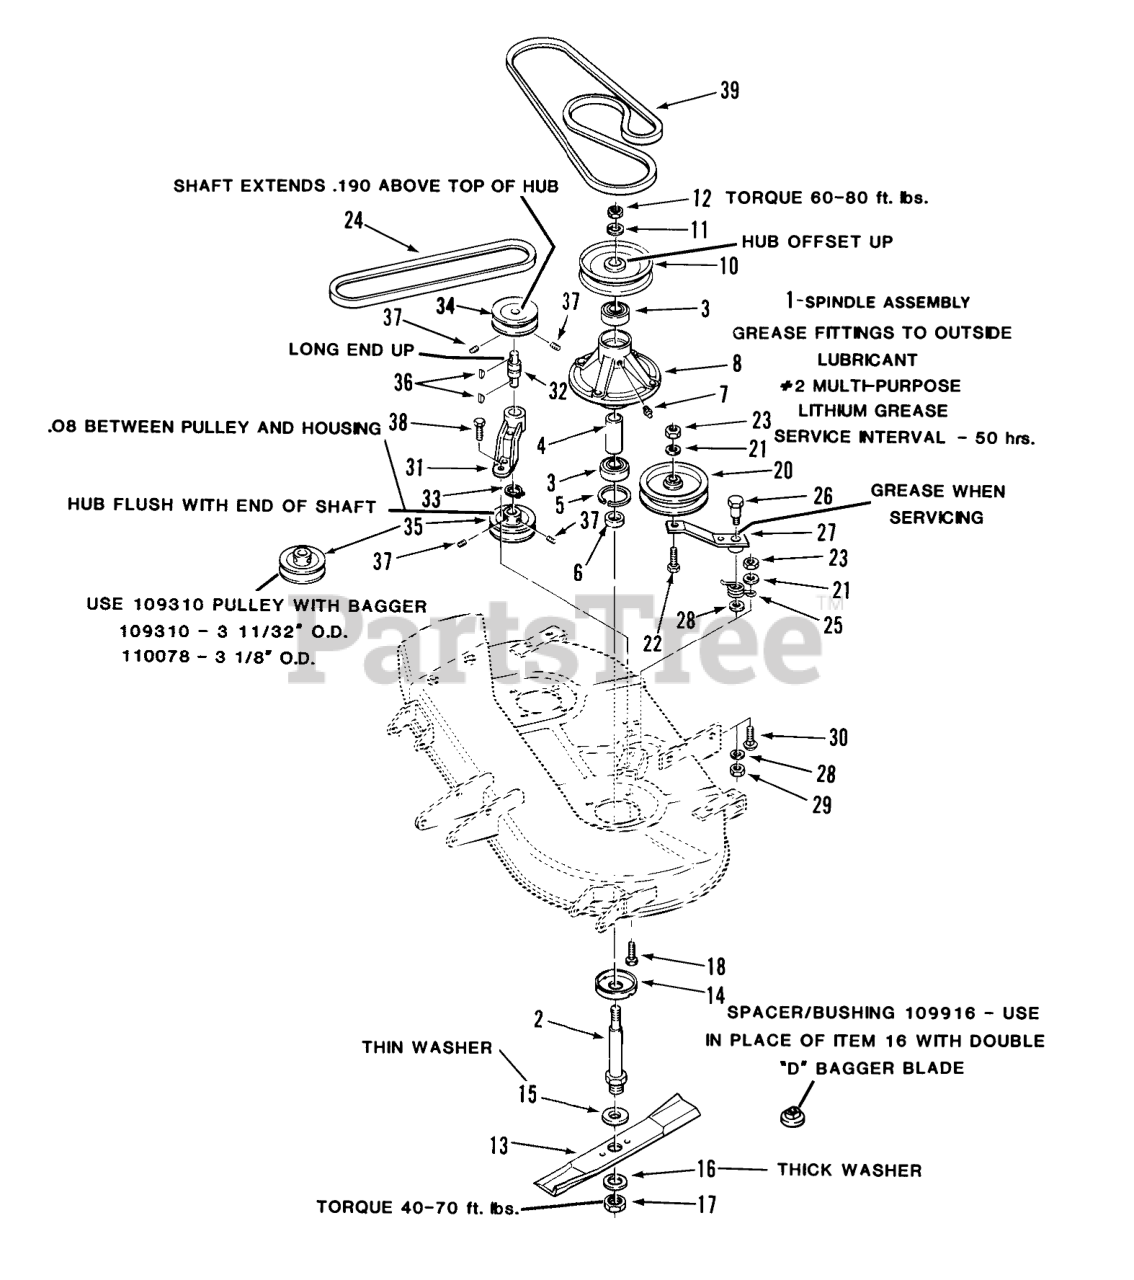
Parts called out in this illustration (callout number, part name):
1	Spindle Assembly,Metric Bearings (includes parts 2 to 8, 14)
2	SHAFT SPINDLE
3	BEARING-BALL
5	Ring-Snap
6	SPACER-BLADE
7	Fitting-Grease
8	HOUSING SPINDLE
10	PULLEY BLADE
11	Lockwasher
12	Jam Nut
13	ASSY BLADE KIT
14	CUP-SPINDLE
15	Washer
16	SpeciaI Washer
17	Nut-Jam
18	Bolt
20	Idler Pulley
21	Washer
22	Bolt
23	Nut
24	V-BELT
25	SPRING-TORSION
26	BOLT-SHOULDER
27	Idler Arm
28	WASHER
29	NUT-JAM(7/16-14)
30	Bolt
31	HOUSING DRIVE BRG R
32	BEARING-INT SHAFT
33	Snap Ring
34	PULLEY
35	PULLEY LOWER
36	KEY-WOODRUFF
37	Set Screw
38	Bolt
39	V-BELT
